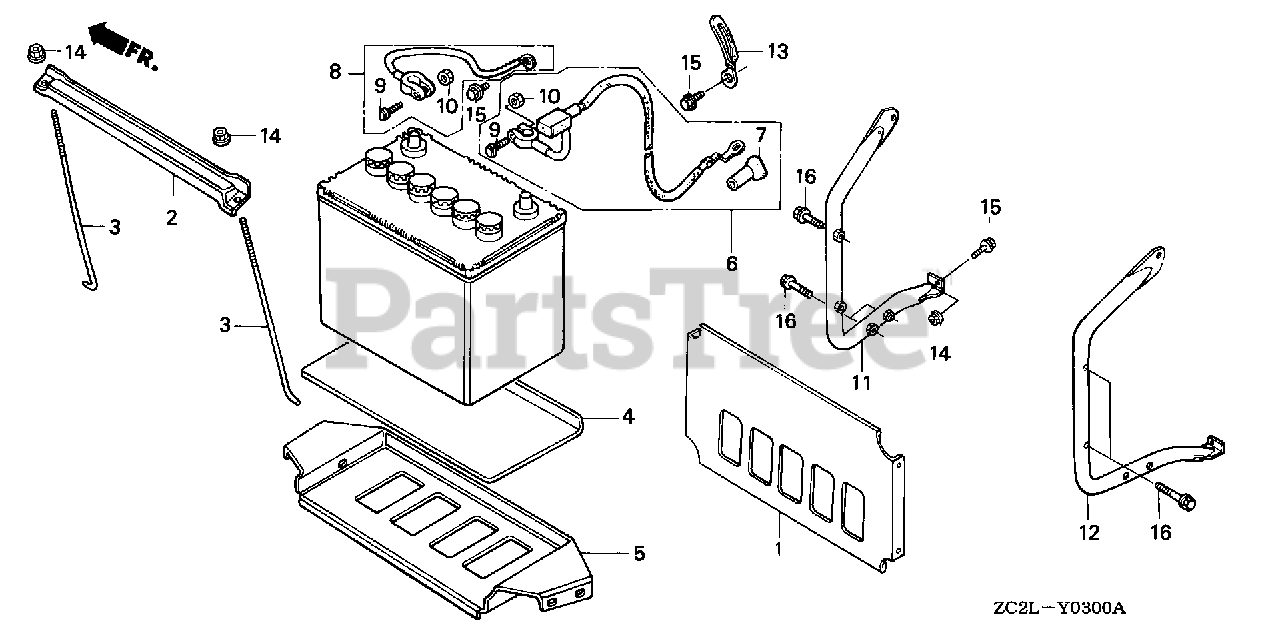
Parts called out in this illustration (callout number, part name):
1	PLATE, BATTERY GUARD
2	PLATE, BATTERY SETTING
3	BOLT, BATTERY SETTING (220MM)
4	PLATE, BATTERY
5	BASE, BATTERY TRAY
6	CABLE ASSY., STARTING
7	COVER, STARTER MOTOR TERMINAL
8	CABLE ASSY., GROUND
9	BOLT, BATTERY TERMINAL (SUMITOMO)
9	BOLT, BATTERY TERMINAL
10	NUT, BATTERY TERMINAL (SUMITOMO)
11	GUARD, FR. BATTERY *NH105* (MAT BLACK)
12	GUARD, RR. BATTERY *NH105* (MAT BLACK)
13	CLIP, HEAD
14	NUT, FLANGE (6MM)
15	BOLT, FLANGE (6X12)
16	BOLT, FLANGE (6X28)
NI	BATTERY (GR.51) (NOT AVAILABLE) (MSDS)
